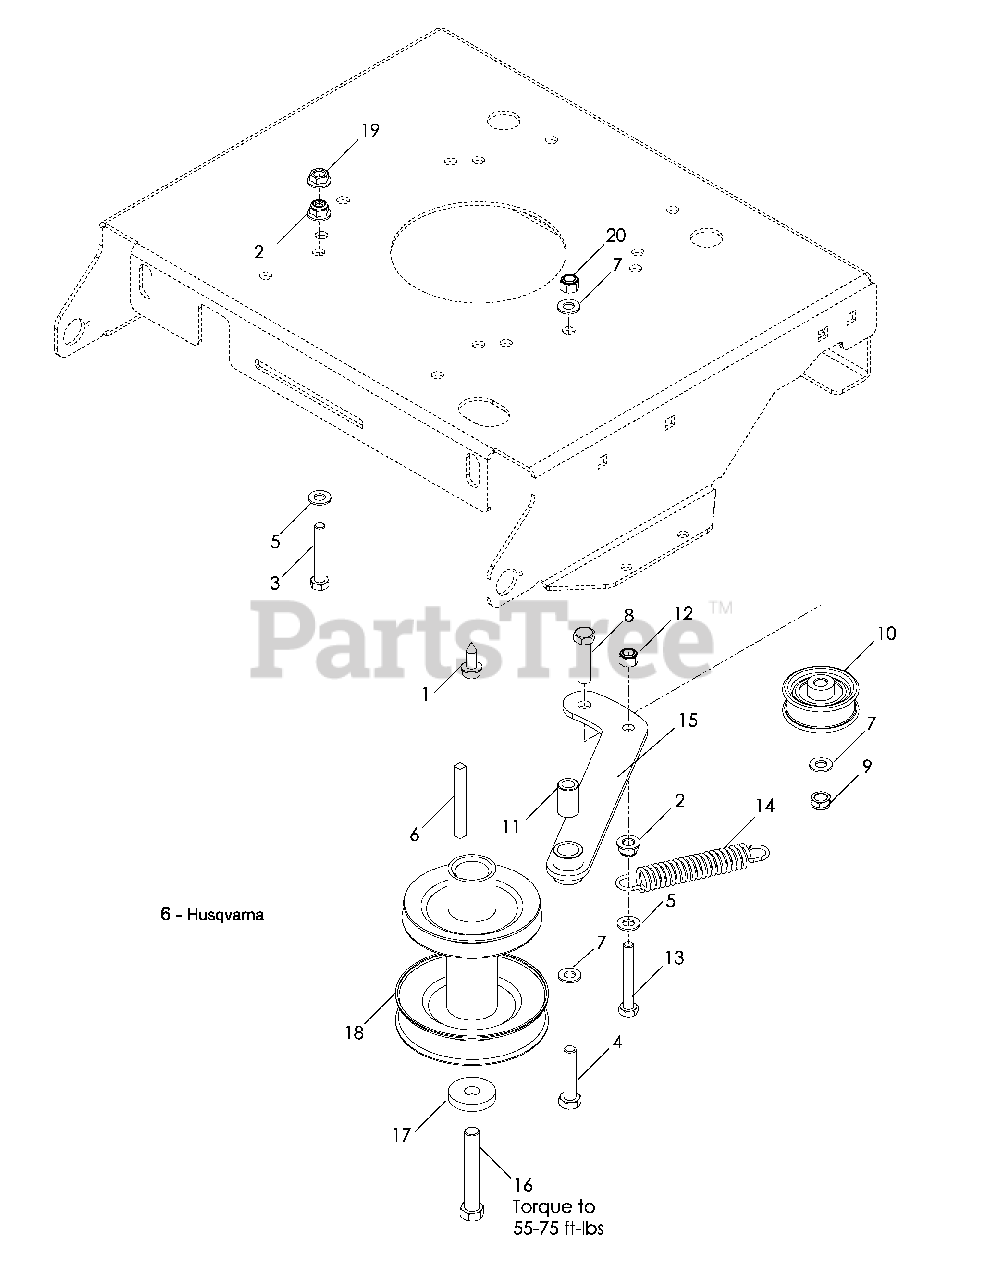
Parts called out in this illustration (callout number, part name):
1	HHFS 3/8-16 x 1 THD FRM
2	NUT 5/16-18 FLANGE NYLOC
3	HCS 5/16-18 x 2
4	HCS 3/8-16 x 1¾
5	WASHER 5/16 SAE FLAT
6	KEY ¼ SQ x 2½ LG
7	WASHER 3/8 FLAT STD
8	HCS 3/8-16 x 1½
9	NUT 3/8-16 HEX JAM NYLOC
10	PULLEY, IDLER
11	BUSHING, METAL
12	NUT 5/16-18 HEX NYLOC
13	HCS 5/16-18 x 2¼
14	SPRING 3½
16	HCS 7/16-20 x 2¾
18	PULLEY, ENGINE
19	NUT 5/16-18 HEX WHIZLK
20	NUT 3/8-16 HEX NYLOC
